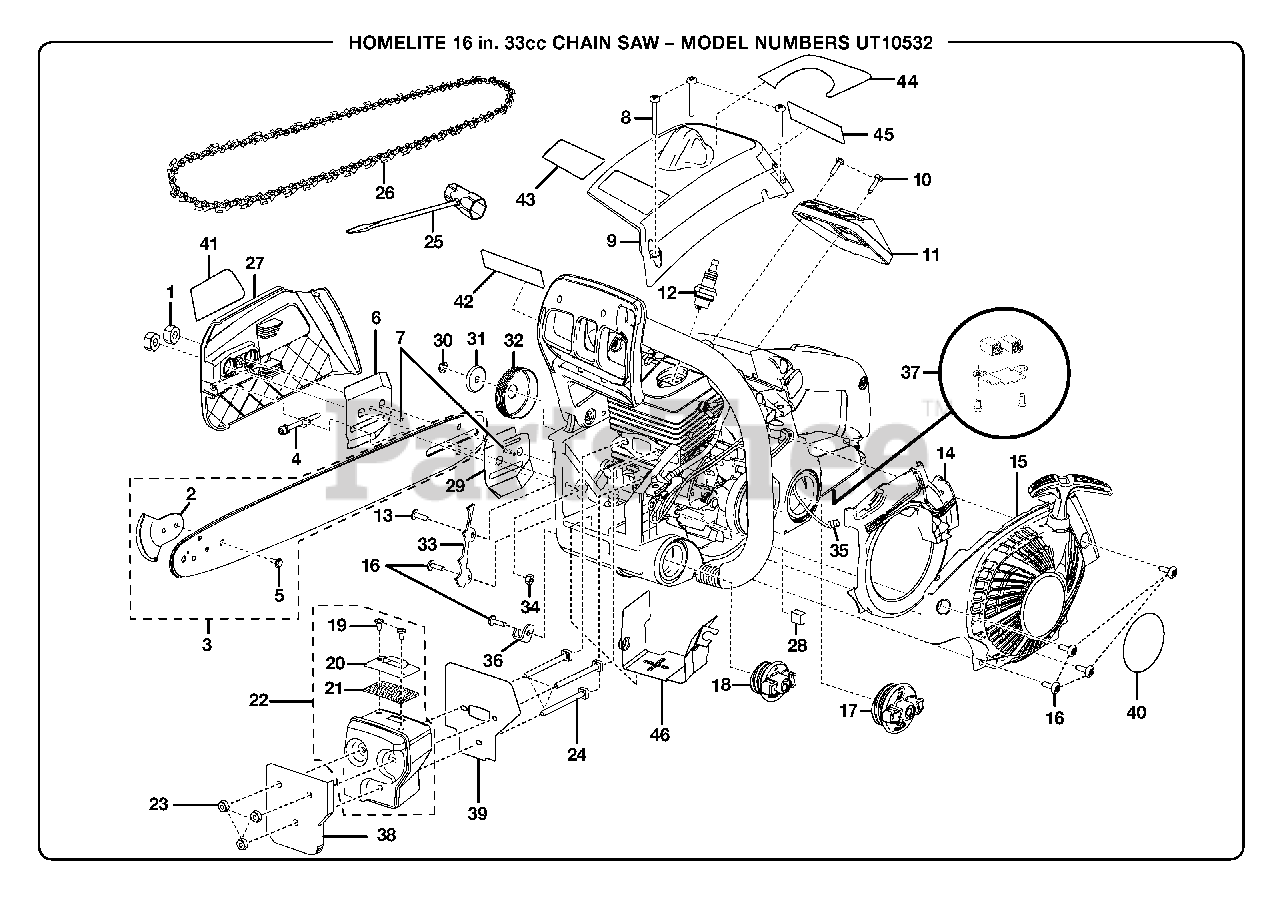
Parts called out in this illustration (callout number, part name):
1	Guide Bar Nut (5/16-18)
2	SAFE-T-TIP
3	Guide Bar (16 in.)
4	Guide Bar Adjustment Assembly
5	SAFE-T-TIP (Screw and Washer)
6	Outer Guide Plate
7	Screw (6-19 x 1/2 in. T.F.)
8	Screw (10-16 x 1-1/2 in. Special)
9	Top Cover
10	Screw (8-16 x 16 mm Torx T.F.)
11	Air Filter Cover
12	Spark Plug (Champion RCJ6Y)
13	Screw (10-24 x 5/8 in. Torx Pan Hd.)
15	Starter Cover Assembly
16	Screw (10-14 x 5/8 in. Torx Pan Hd.)
17	Fuel Cap Assembly
18	Oil Cap Assembly
19	Screw (8-32 x 5/16 in.)
21	Spark Screen
22	Muffler Assembly
23	Lock Nut (10-32)
24	Bolt (10-32 x 63.6 mm Square Hd.)
25	Combination Wrench
27	Chain Cover Assembly
28	Pre-Filter
29	Inner Guide Plate
30	E-Ring
31	Cupped Washer
32	Sprocket Drum & Bearing Assembly
33	Bumper Spike
34	Lock Nut (10-24)
35	Fuel Filter
36	Chain Guard
37	Tool Holder Assembly
38	Heat Shield
39	Muffler Gasket
40	Starter Housing Decal
41	Clutch Cover Label
42	Chain Brake Label
43	Warning Label
44	Starting Instruction Decal
45	Icon Warning Label
46	Heat Shield
